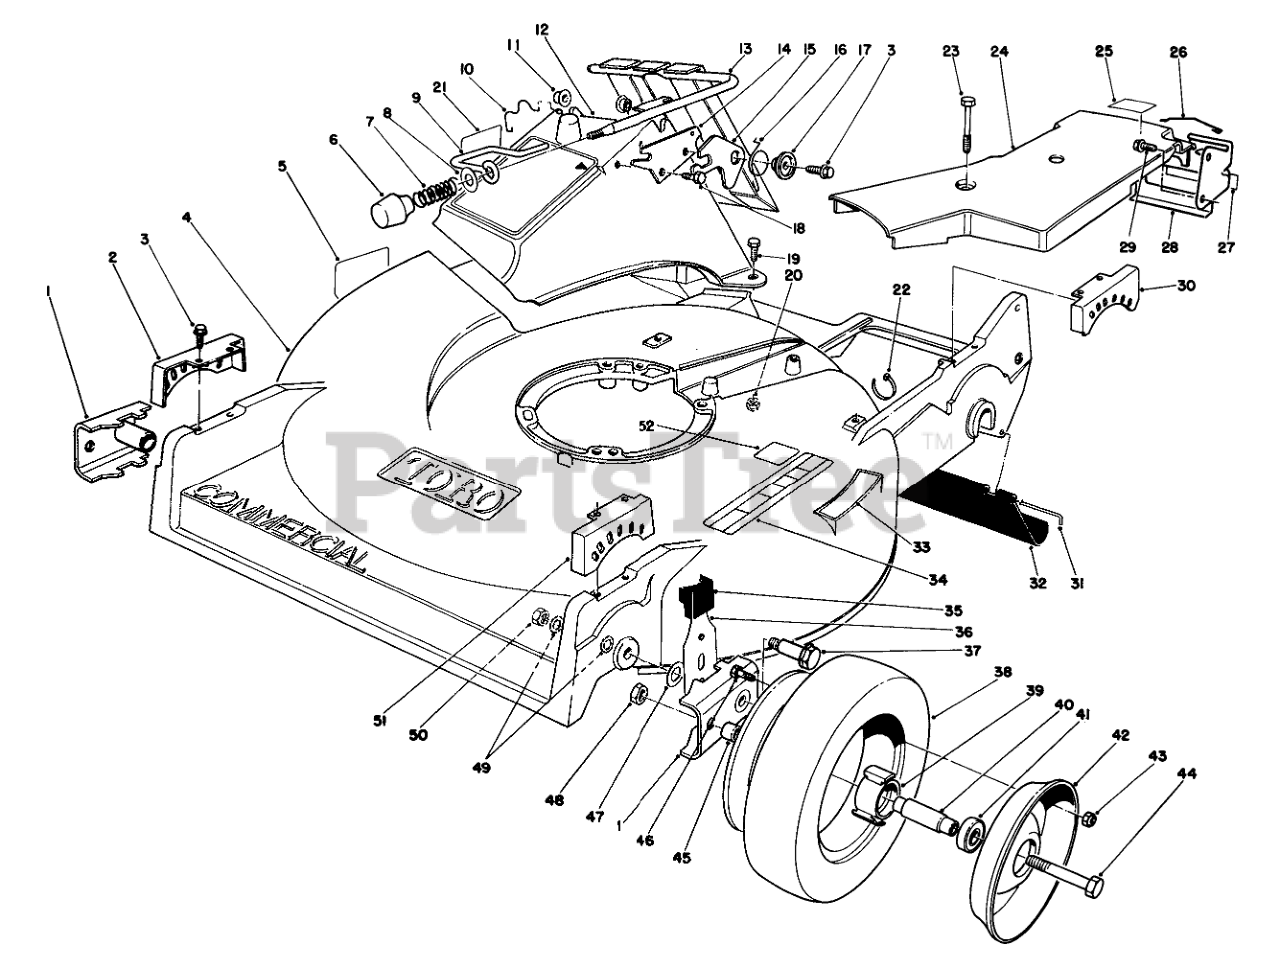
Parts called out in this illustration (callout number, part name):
1	ARM-PIVOT, FRONT
2	QUADRANT-FRONT, RH
3	SCREW-HWHTF
4	Housing-Commercial (Incl. Ref. #5, 33 & 34)
5	Decal Danger
7	COMPRESSION SPRING
8	WASHER-FLAT
9	DOOR LATCH
10	DOOR RETAINER
11	BUSHING-NYLON
12	DISCHARGE CHUTE B
13	DOOR & HANDLE WA
14	DOOR LATCH PLATE
15	SAFETY LATCH
16	TORSION SPRING
17	DOOR SPACER
18	SCREW-HWH
19	SCREW-HH
20	NUT-LOCK, NI
21	DECAL - DANGER
22	TIE-CABLE
23	SCREW-HHFTF
24	COVER-BELT
25	Label-Grease
26	RETAINER-CABLE
27	DECAL-POSITION, GEAR
28	BRKT-TRACTION ADJ.
29	SCREW-HWHTF
30	QUADRANT-REAR, LH
31	ROD-SHIELD
32	SHIELD-TRAILING
33	DECAL - STEP PAD INT'L
34	Decal-Safety Instructions
35	KNOB-ARM
36	FRONT SPRING ARM ASM
37	WHEEL BOLT
39	HUB-BEARING
40	SPACER-BEARING
41	BEARING-WHEEL
42	Wheel-Half
43	NUT-LOCK, NI
44	SCREW-HH
45	SPACER-WHEEL
46	SCREW-HH
47	WASHER-THRUST
48	NUT-LOCK, CONE
49	WASHER
50	Nut
51	QUADRANT-FRONT, LH
52	Decal-Noise Level
